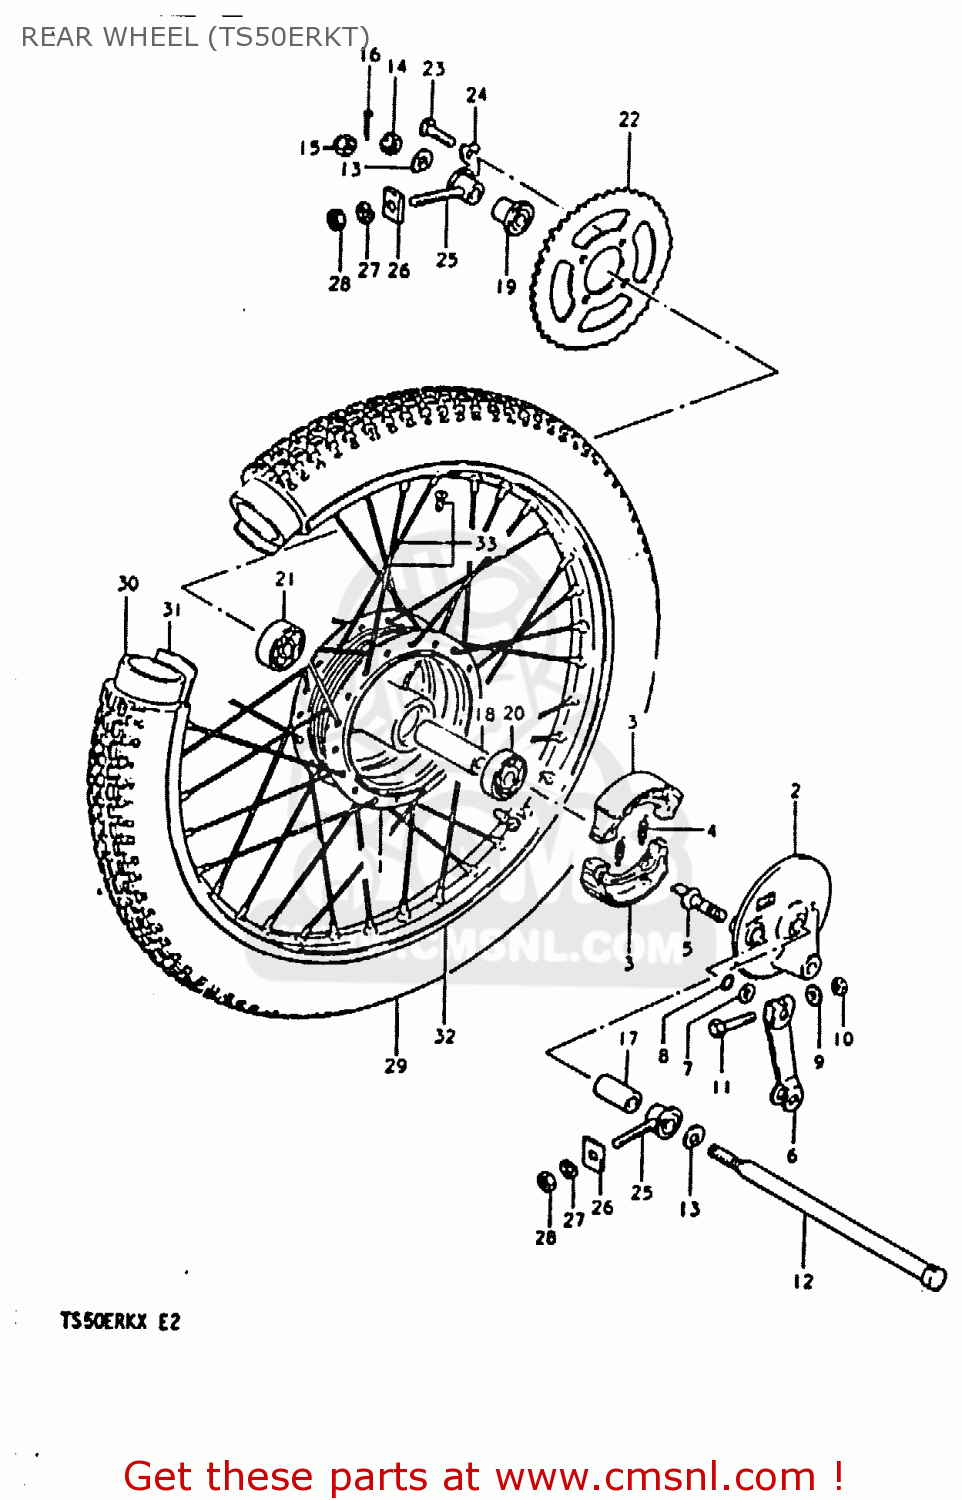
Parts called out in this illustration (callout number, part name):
1	DRUM, REAR HUB
2	PANEL,REAR BRAKE ANCHOR
3	SHOE,BRAKE (MCA)
4	SPRING(L:34)
5	CAM,FRONT BRAKE
6	LEVER,RR BRAKE CAM
7	WASHER (14.5X22X1.6)
8	O-RING (D:2.4 ID:13.8)
9	WASHER
10	NUT
11	BOLT(6X33)
12	AXLE,RR
13	WASHER,RR AXLE
14	NUT 12MM
16	COTTER PIN
17	SPACER, AXLE RH
18	SPACER(12.6X19X91)
19	SPACER, REAR AXLE LH
20	BEARING
21	BEARING
22	SPROCKET, REAR (NT:49)
23	BOLT(8X25)
24	WASHER
25	ADJUSTER, CHAIN
26	ADJUSTER,CHAIN
27	LOCK WASHER
28	NUT
29	TIRE
30	TUBE,INNER
31	PROTECTOR,INNER TUBE
32	RIM, WHEEL
33	SPOKE SET,REAR WHEEL
